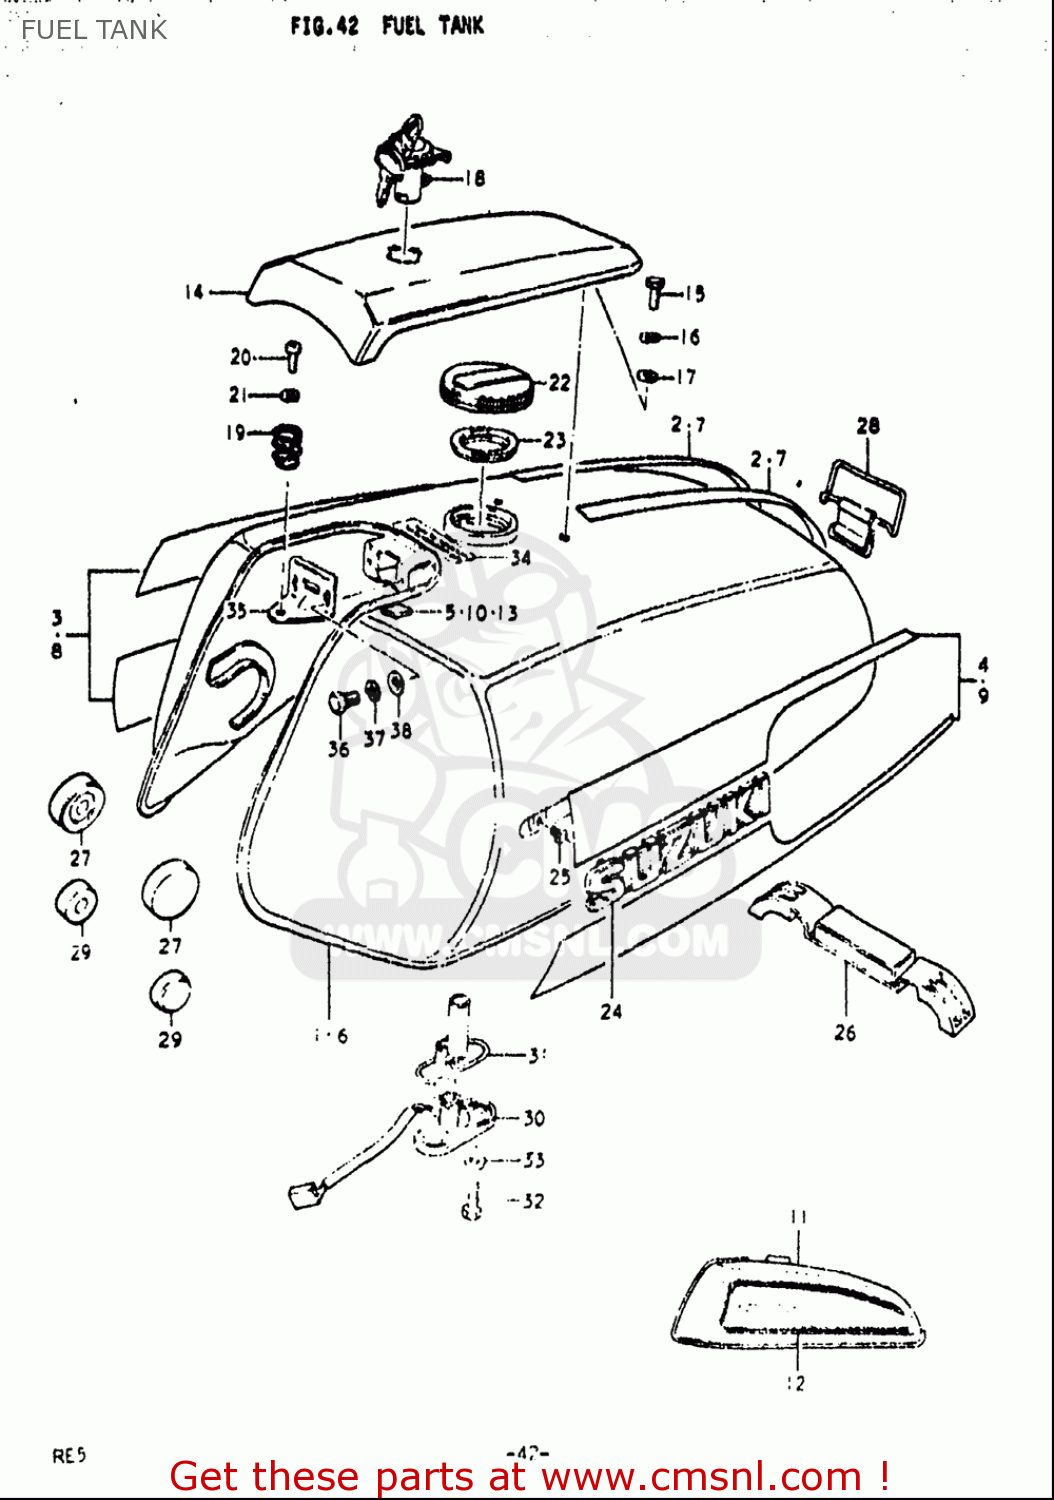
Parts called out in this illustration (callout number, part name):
5	CUSHION,FUEL TANK FR COVER
10	CUSHION,FUEL TANK FR COVER
13	CUSHION,FUEL TANK FR COVER
15	BOLT
16	WASHER,LOCK
17	WASHER
18	LOCK,FUEL TANK FR COVER
19	SPRING
20	SCREW
21	WASHER,LOCK
22	CAP ASSY,FUEL TANK FILLER
25	NUT
27	CUSHION
28	BAND
29	CUSHION
32	BOLT
35	HOLDER,FUEL TANK FRONT COVER
36	BOLT
37	WASHER,LOCK
38	WASHER
